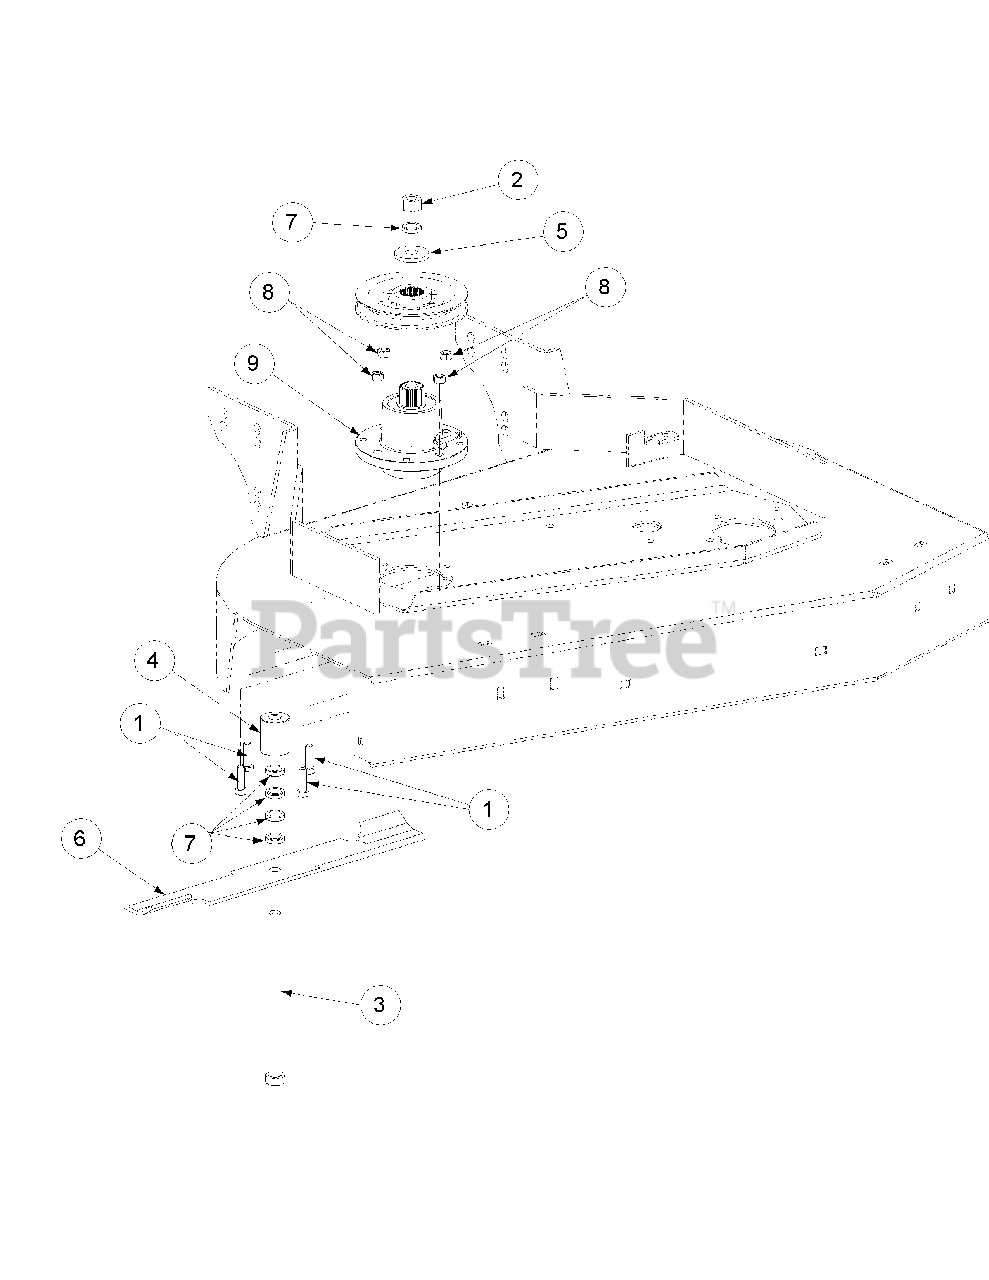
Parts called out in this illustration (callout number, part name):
1	Hex Cap Screw, 3/8-16 x 1-1/2
2	Hex Nut, 5/8-11
3	Hex Cap Screw, 5/8-11 x 9
4	Blade Spacer, .630 x 1.500 x 1.850
5	Flat Washer, .656 ID x 1.313 OD
6	18" Rotary Blade Blade
7	Spacer, 5/8 ID, 1/4 Thick
8	Hex Nut Flange Lock, 3/8-16
9	Spindle Assembly
